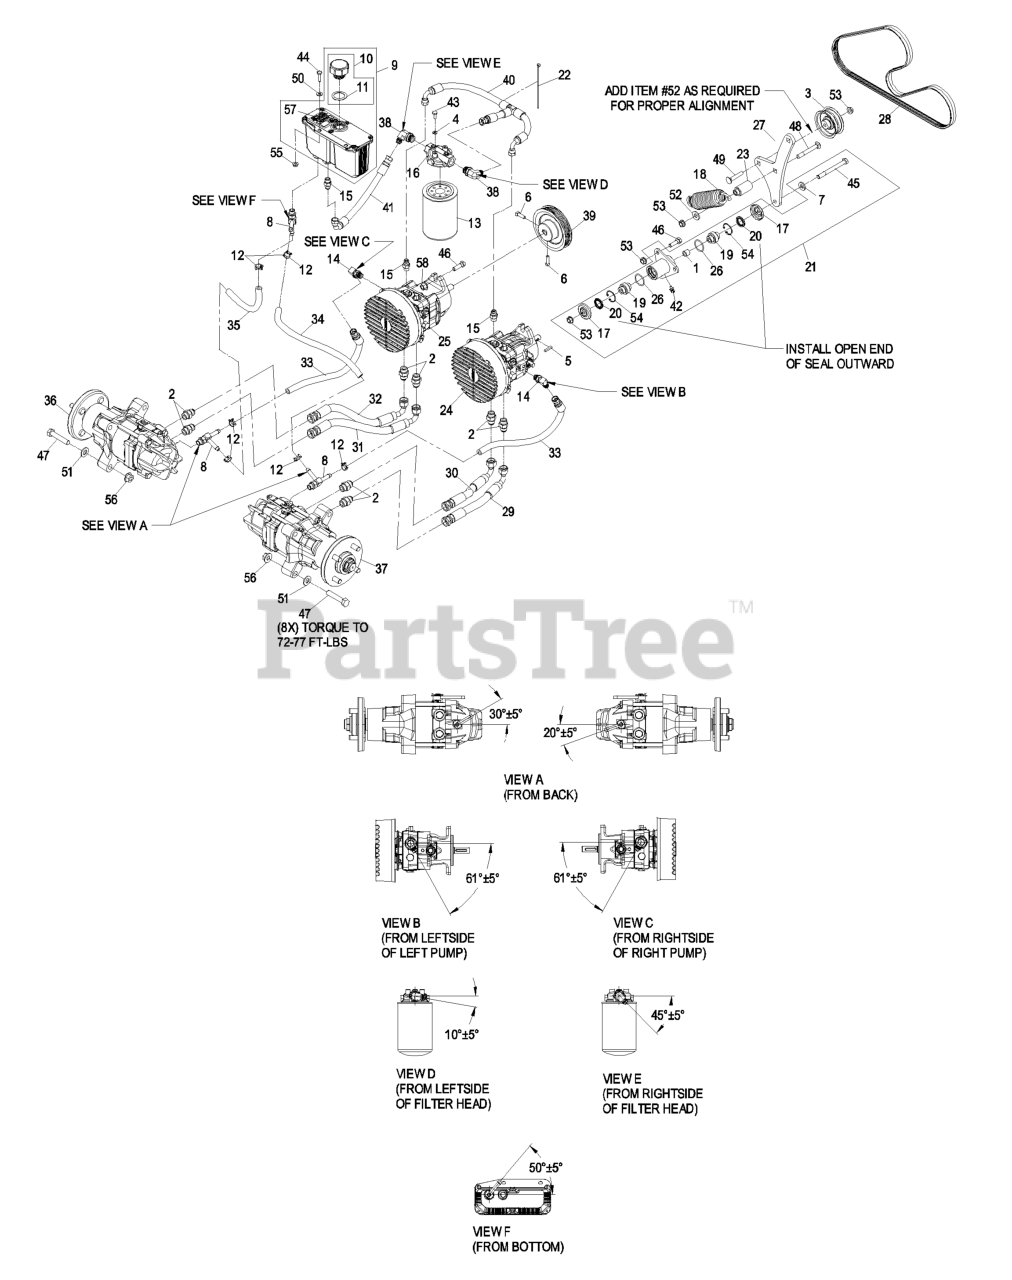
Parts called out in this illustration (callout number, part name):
1	BUSHING-LEVER, LIFT
2	FITTING-STRAIGHT
3	PULLEY-FLAT IDLER
4	WASHER-LOCK
5	KEY
6	SCREW-SET
7	WASHER-BELLEVILLE
8	ADAPTER-RUN, TEE
9	HYD RESERVOIR ASM
10	KIT,HYD RES CAP W/GASKET
11	GASKET-CAP
12	CLAMP-HOSE
13	FILTER,XP HYD 25 MICRON
14	FITTING-90 DEG
15	FITTING-STRAIGHT
16	HEAD-FILTER
17	GUARD-TOP
19	BEARING-SPHERICAL
20	SEAL-LIP, SINGLE
21	KIT,'04 XP PUMP IDLER
22	TIE-CABLE
23	SPACER, SPRING 1.75 (PLAT
24	PUMP,HYDRO PR W/FAN LH
25	PUMP,HYDRO PJ W/FAN RH
25	PUMP,HYDRO PR W/FAN RH
27	ARM,IDLER
28	BELT,5K EL-54.50
29	HOSE,HYDRAULIC LH LOWER
30	HOSE,HYDRAULIC LH UPPER
31	HOSE,HYDRAULIC RH LOWER
32	HOSE,HYDRAULIC RH UPPER
33	ASM,CASE DRAIN
34	HOSE,CASE DRAIN LH
35	HOSE,CASE DRAIN RH
36	MOTOR,PRM18-RH
37	MOTOR,PRM18-LH
37	MOTOR,PRM20-LH
38	ADAPTER,90 DEG
39	SHEAVE,5K POLY-V
40	ASM,CHARGE HOSE TEE
41	ASM,CHARGE HOSE
42	FITTING-GREASE, 90 DEG
43	SCREW-HH
44	SCREW-HH
45	SCREW-HH
46	SCREW-HH
47	SCREW-HH
48	SCREW-CARR
49	SCREW-HH
50	WASHER-FLAT
51	WASHER-FLAT
52	WASHER-FLAT
53	NUT-HHF, WHIZ
54	RING-SNAP
56	NUT-HHF
58	NUT-FLANGE
59	WASHER-FLAT
